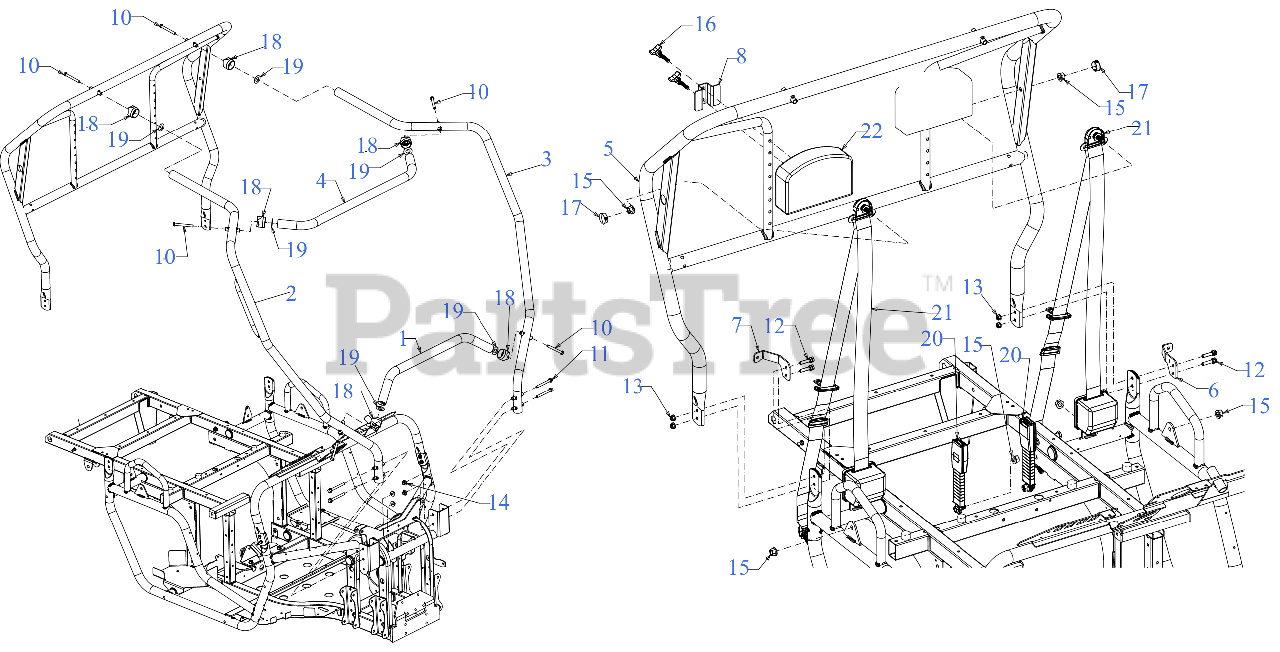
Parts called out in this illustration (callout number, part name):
10	HEX CAP SCREW 3/8-16:3.25
11	HEX FLANGE BOLT 3/8-16:3.50
12	SCREW 5/16-18 x 1.5 LG
13	FLANGE LOCK NUT 5/16-18
14	FLANGE LOCK NUT
15	FLANGE LOCK NUT
16	KNOB ASSEMBLY (5/16-18 x 2.00)
17	PANEL PLUG
18	TUBE COLLAR
19	FLAT WASHER .760ID X1.49OD x .06
20	3-POINT SEAT BELT
21	3-POINT SEAT BELT
22	HEADREST PAD
